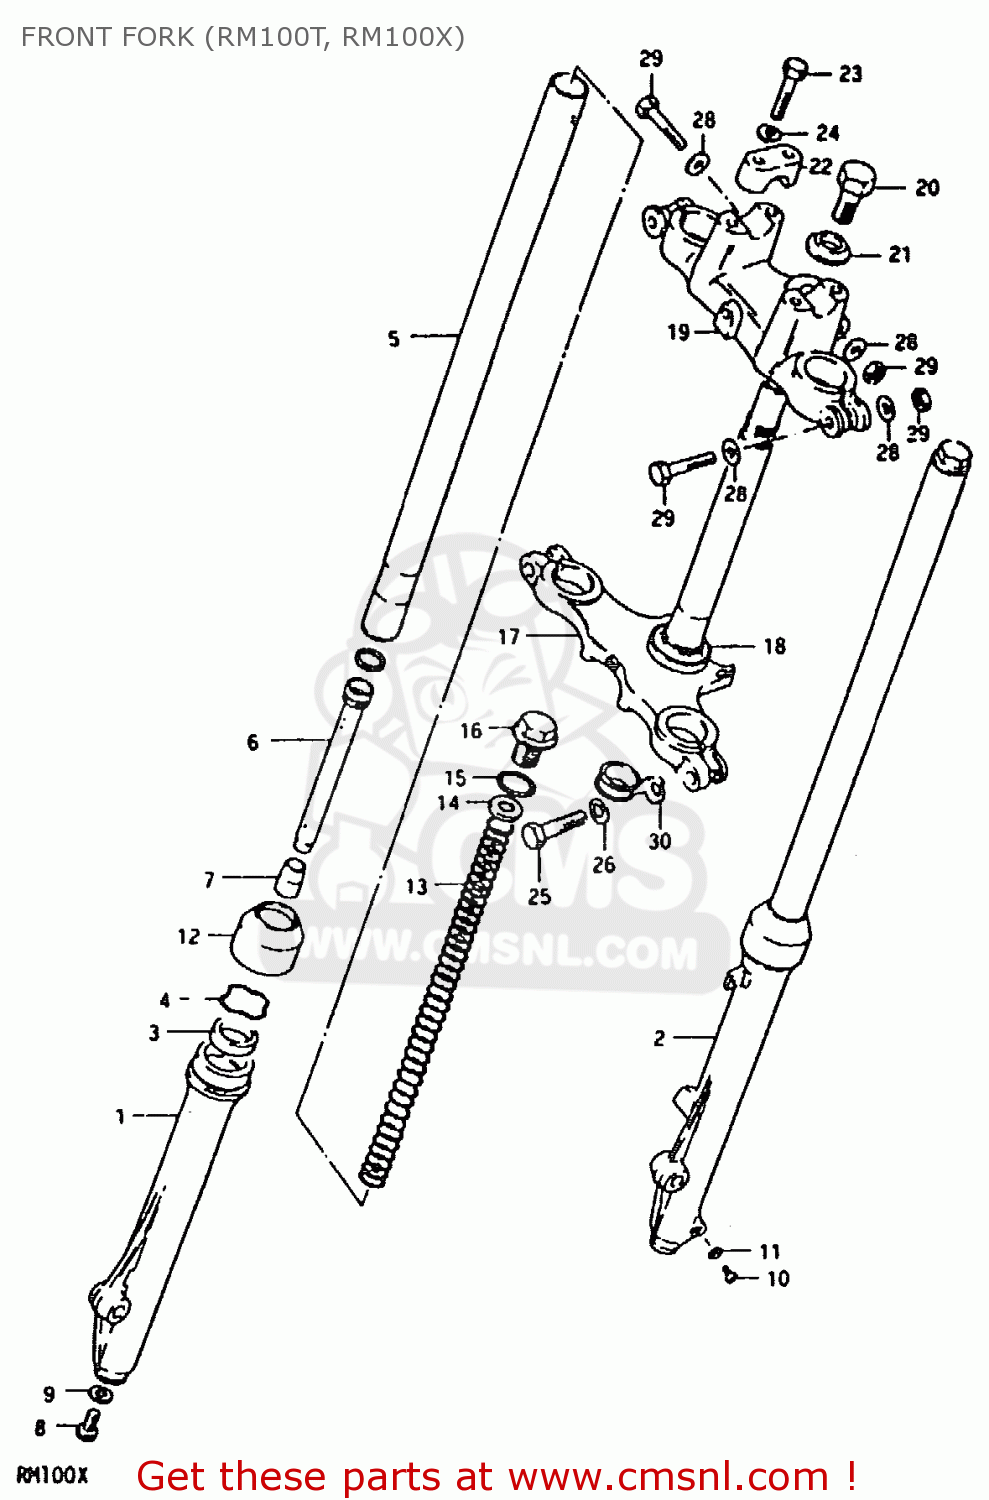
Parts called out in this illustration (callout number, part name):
1	TUBE,OUTER,RIGHT
2	TUBE,OUTER,LEFT
3	SEAL,OIL
4	5
5	TUBE,FORK,INNER
6	CYLINDER,FRONT FORK
7	PIECE,OIL LOCK
8	BOLT,FORK CYLINDER(10X25)
9	GASKET (NAS)
10	SCREW
11	GASKET,DRAIN,PLUG (NAS)
12	SEAL,DUST
13	SPRING
14	GUIDE,FRONT FORK SPRING C
15	O RING
16	CAP,FORK INNER TUBE
17	STEM,STEERING
18	RACE,STEERING,OUTER,UPPER
19	HEAD,STEERING STEM
20	BOLT
21	WASHER
22	HOLDER,HANDLEBAR
23	BOLT
24	LOCK WASHER
25	BOLT
26	WASHER,LOCK 12
27	BOLT 8X55
28	WASHER
29	NUT 8MM
30	GUIDE,CABLE
